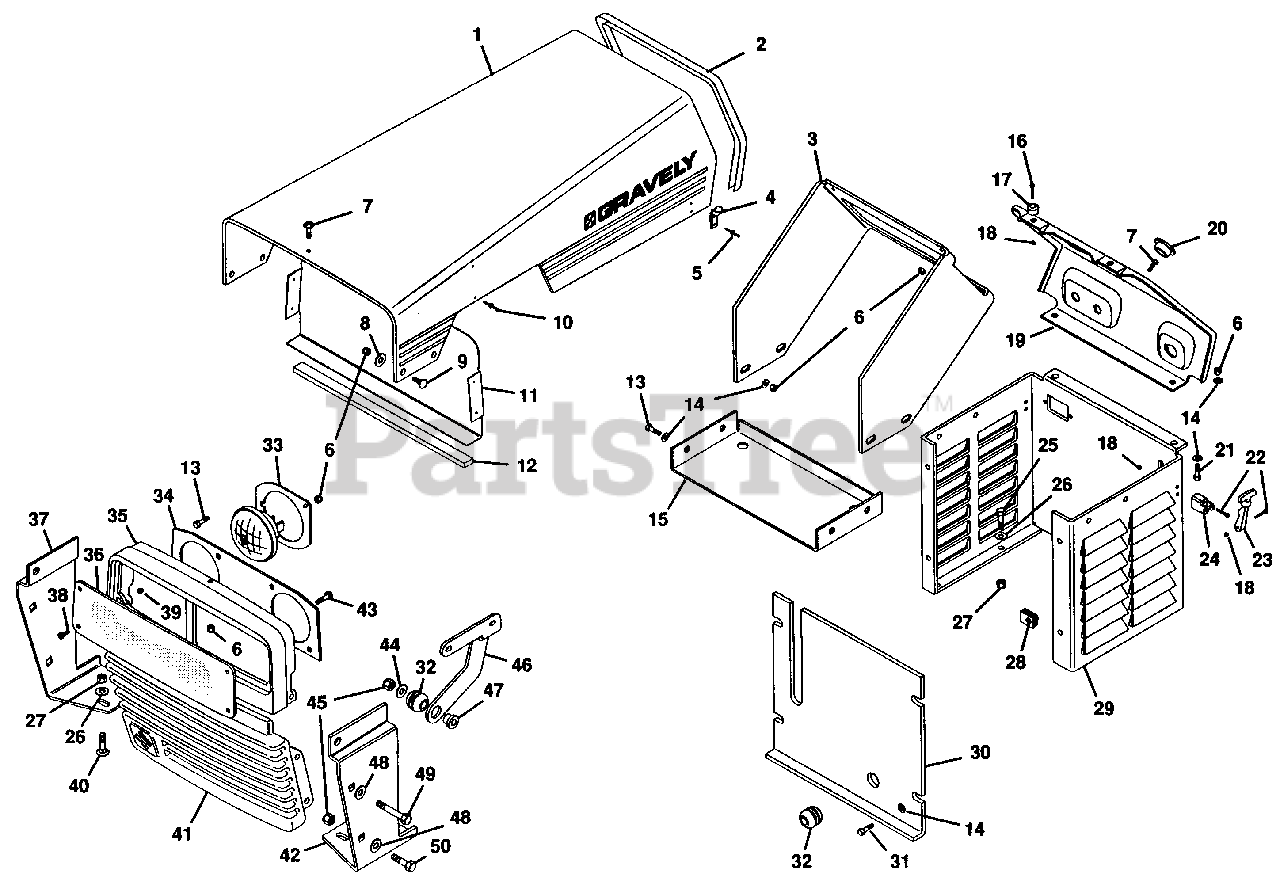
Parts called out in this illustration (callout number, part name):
1	Hood, GEM Silkscreen
2	Strip, Cowl
3	Bracket, Support
4	Keeper
5	Rivet, Dome Head
6	Nut, Lock 1/4-20
7	Screw, Mach. 1/4-20 PHD
8	Washer, Flat .281 x .625 x .065
9	Bolt, 1/4-20 x .75 Rd Hd Sq Nk
10	Rivet, Pop .125 x .232
11	Baffle
12	Pad, Baffle
13	Bolt, Hex 1/4-20 x 1.00
14	Washer, Flat .281 x .625 x .065
15	Tray, Battery
16	Screw, Mach. 6-32 x .625 PHD
17	Bumper
18	Nut, Mach. Lock 6-32
19	Panel, Silkscreen Control
20	Bushing, Flange Nylon
21	Bolt, Hex 1/4-20 x .625
22	Screw, Mach. 6-32 x 1.0 PHCR
23	Latch, Flexible Draw
24	Block, Tie-Down
25	Bolt, Hex 5/16-18 x 1.00
26	Washer, Flat .344 x .688 x .065
27	Nut, Lock 5/16-18
28	Nut, Retainer
29	Panel, Silkscreen
30	Cover, Hydraulic Tank
31	Bolt, Hex 1/4-20 x .75
32	Grommet
33	Ring, Headlight Retainer
34	Panel, Headlight Reflector
35	Headlight, Bezel
36	Panel, Headlight Lense
37	Bracket, Grille(R.H.)
38	Screw, Mach. 10-24 x .75 PHD
39	Nut, Lock 10-24
40	Bolt, Carriage 5/16-18 x 1.0
41	Casting, Grille
42	Bracket(L.H.)
43	Screw, 1/4-20 x .50 Self Tapping
44	Washer, Flat .438 x 1.000 x .083
45	Nut, Lock 3/8-16
46	Hinge, Hood L.H.
46	Hinge, Hood R.H.
47	Spacer
48	Washer, Flat .406 x .812 x .065
49	Bolt, Hex 3/8-16 x 2.00
50	Bolt, Hex 3/8-16 x 1.25
